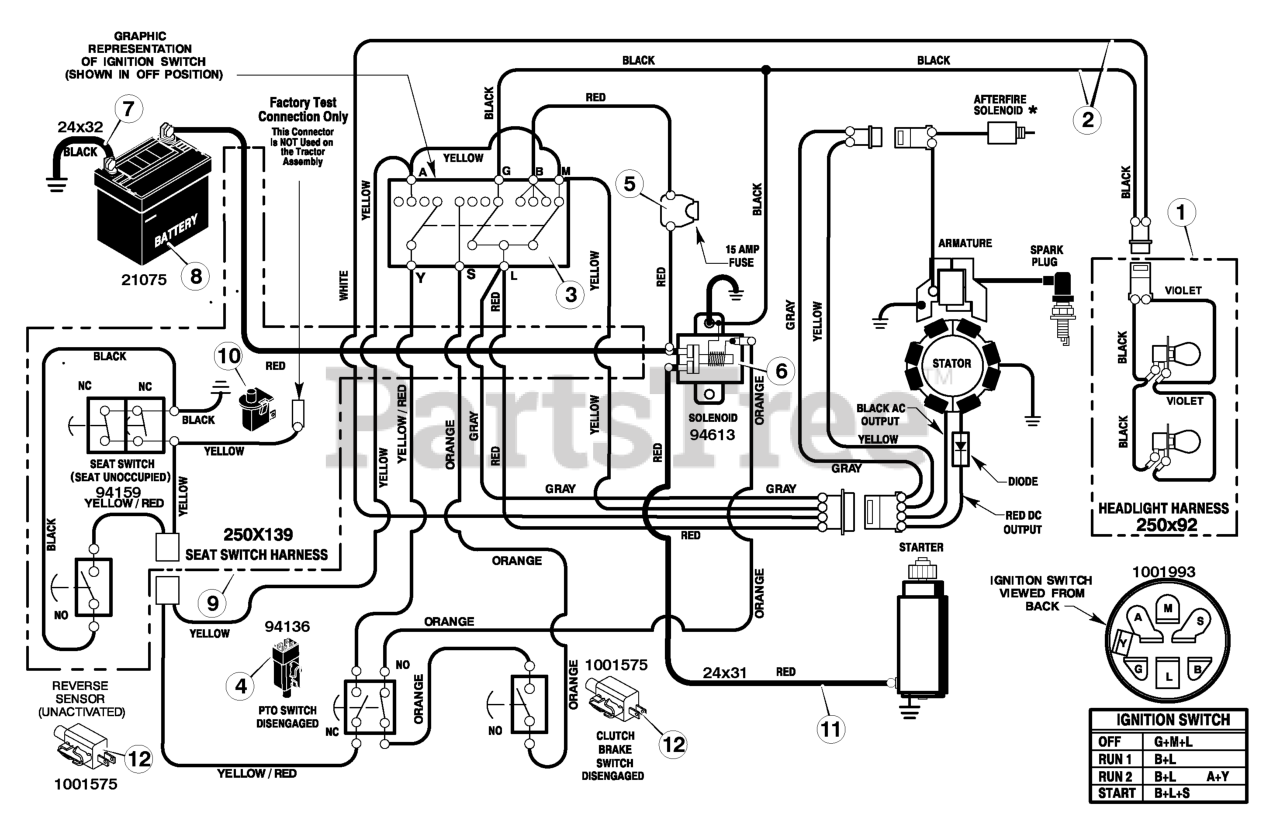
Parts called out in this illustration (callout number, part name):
1	Harness, Light Wire
2	Harness, Chassis Wire
3	Switch, Ignition
4	Switch, Limit (PTO)
6	Solenoid
7	Cable, Battery Ground
8	Battery
9	Harness, Seat Switch Wire
10	Switch, Seat Sensor
12	Switch, Select Reverse3 / Clutch Brake
